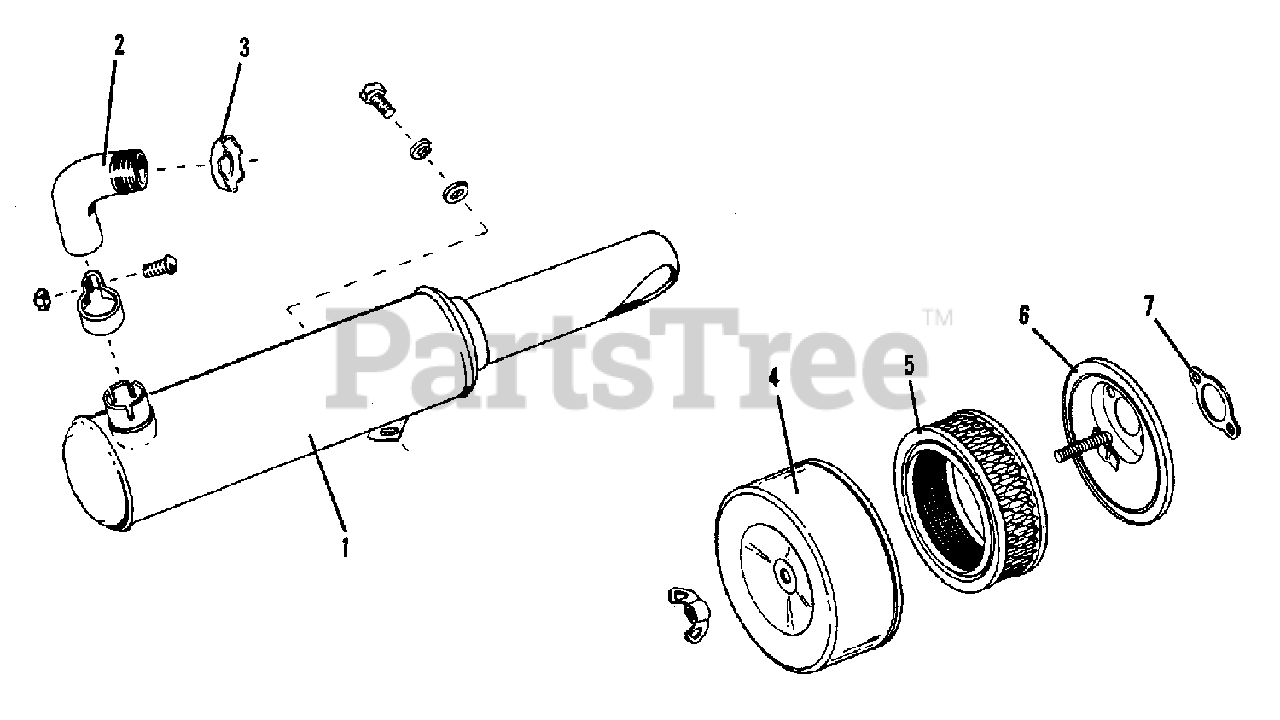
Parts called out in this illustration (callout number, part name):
1	MUFFLER ASSEMBLY
1	CAPSCREW, 7/16NC x 7.8
1	LOCKWASHER, 7/16
1	NUT, 7/16NC
2	ELBOW, Exhaust
4	COVER, Air Cleaner
5	ELEMENT, Air Cleaner
6	BASE ASSEMBLY, Air Cleaner
6	NUT, Wing
7	GASKET, Air Cleaner (Included in Engine Gasket Set)
